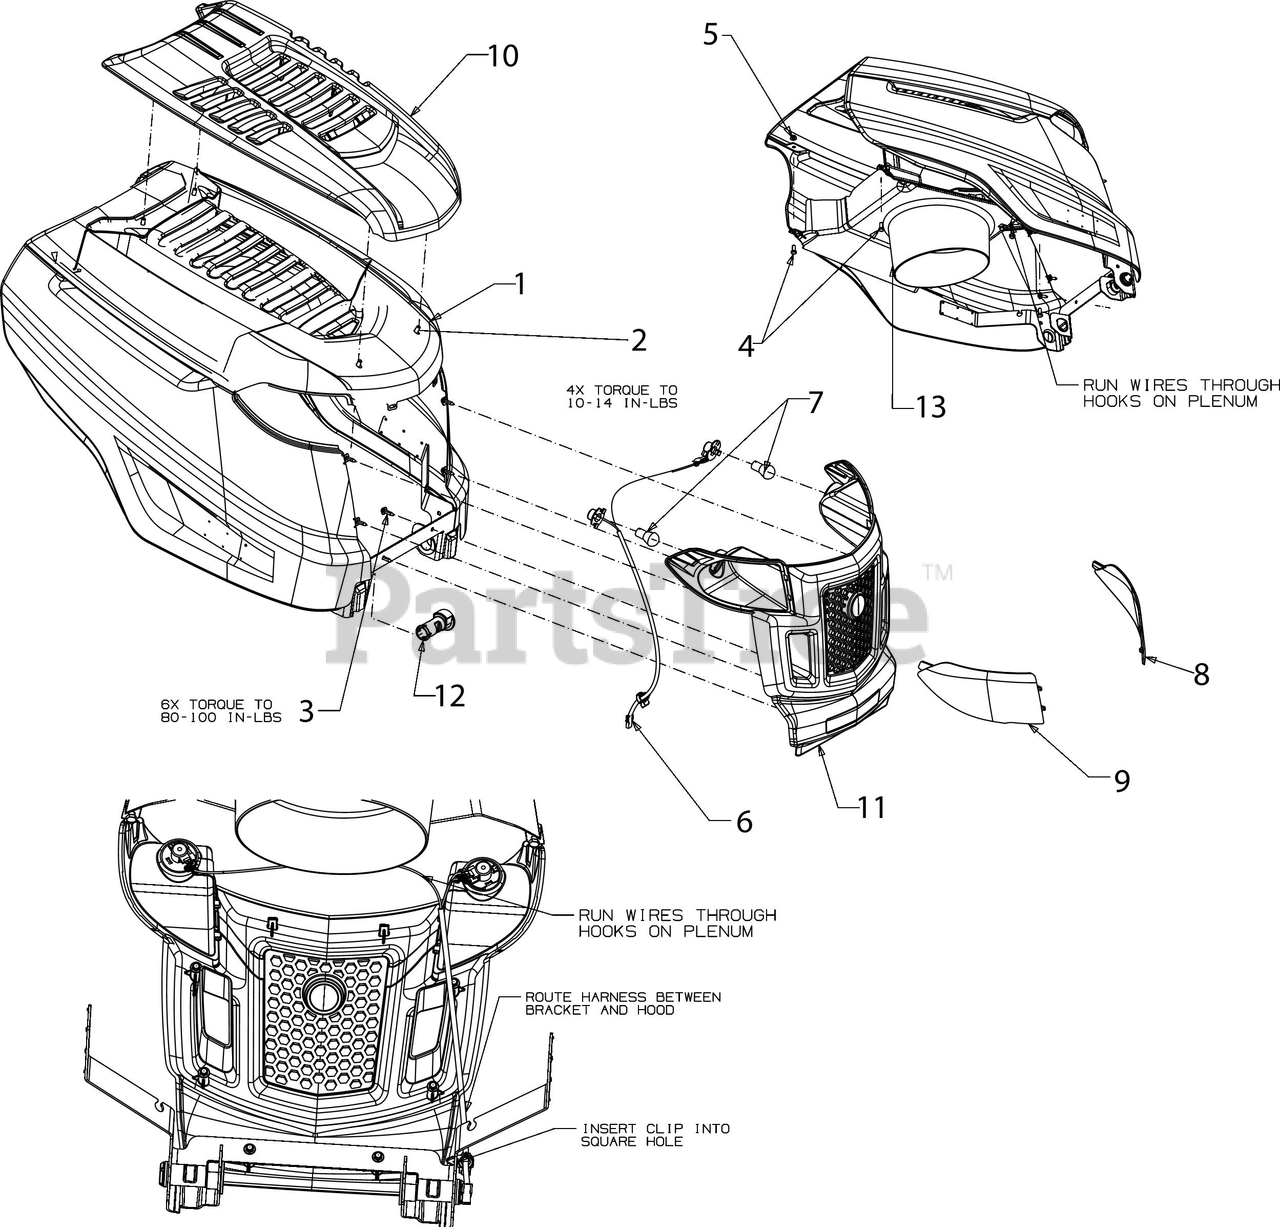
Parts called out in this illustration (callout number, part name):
1	HOOD ASSEMBLY(K STYLE)
2	HEX SCREW 1/4-15 x .50
3	SCREW 1/4-10 x .750
4	SCREW 1/4-20 x .620 GR5
5	FLANGE LOCK NUT
6	HEADLIGHT HARNESS
7	MINIATUURE BULB 12V
8	LENS (LH)
9	LENS (RH)
10	HOOD SCOOP
11	GRILLE (K STYLE)
12	HOOD PIVOT PIN
13	PLENUM (K-STYLE)
